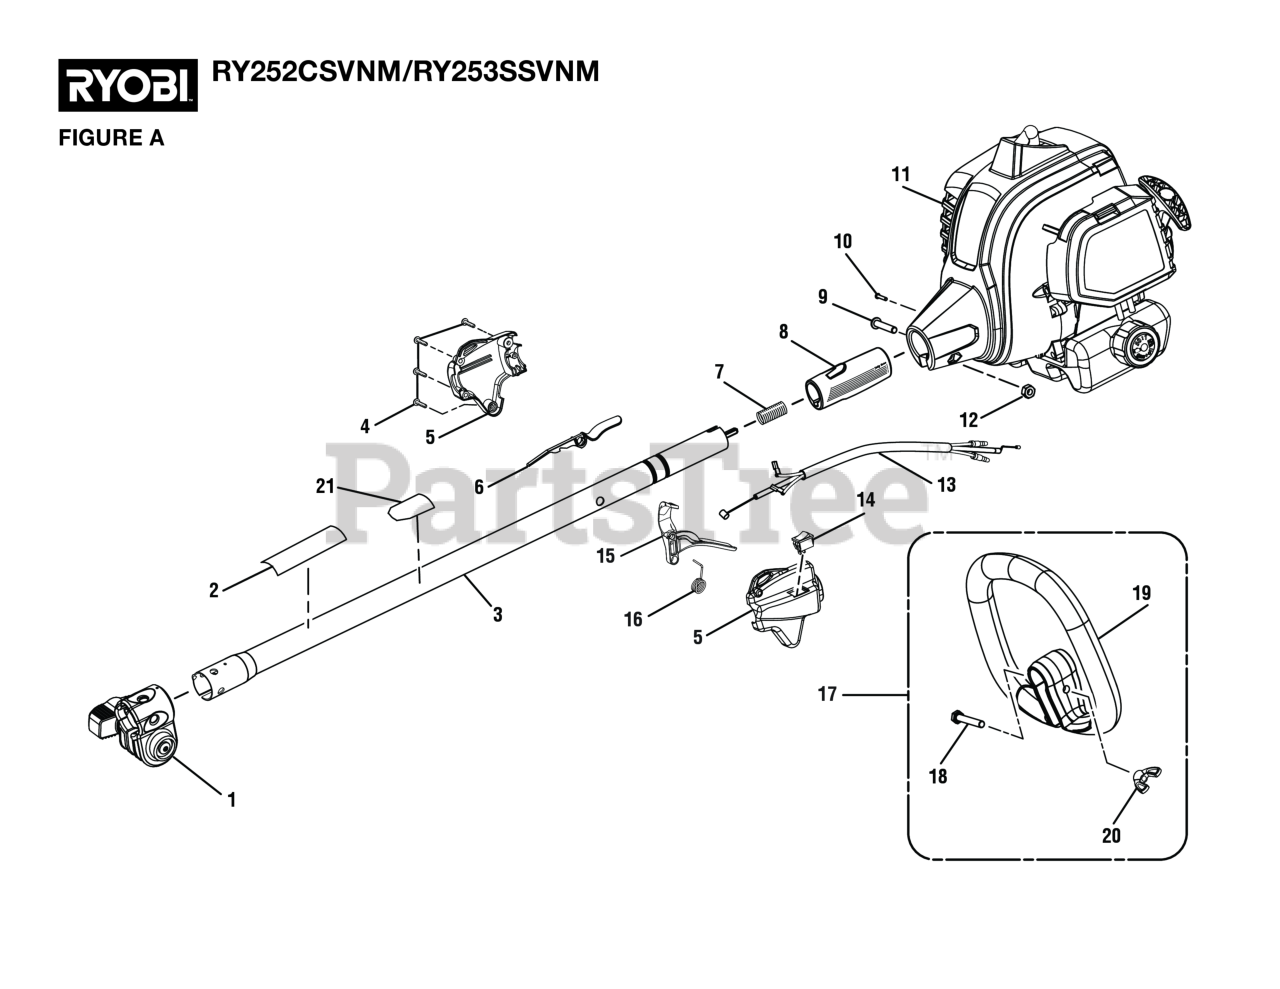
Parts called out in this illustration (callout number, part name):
1	Boom Clamp Assembly
2	Attachment Label
3	Upper Boom Assembly (Inc. Key Nos. 1-2)
4	Screw (M4 x 20 mm, T20 Torx Pan Hd. S.T.)
5	Control Handle Assembly (Inc. Key No. 6)
6	Trigger Lock
7	COMPRESSION SPRING
8	Rear Handle Grip
9	Screw (M6 x 30 mm, T27 Torx Button Hd.)
10	Screw (M4 x 8 mm, T25 Torx Pan Hd. T.F.)
11	Powerhead Assembly w/Labels
12	Hex Nut (M6.3 x 1)
13	Throttle Cable and Wire Assembly
14	Stop Switch (Momentary Contact)
16	Torsion Spring (Throttle Trigger)
17	Auxiliary Handle Assembly
18	Screw (1/4-20 x 40 mm, Cap Hex Hd.)
19	Front Handle
20	Wing Nut (1/4-20, Plastic)
21	Warning Icon Label
